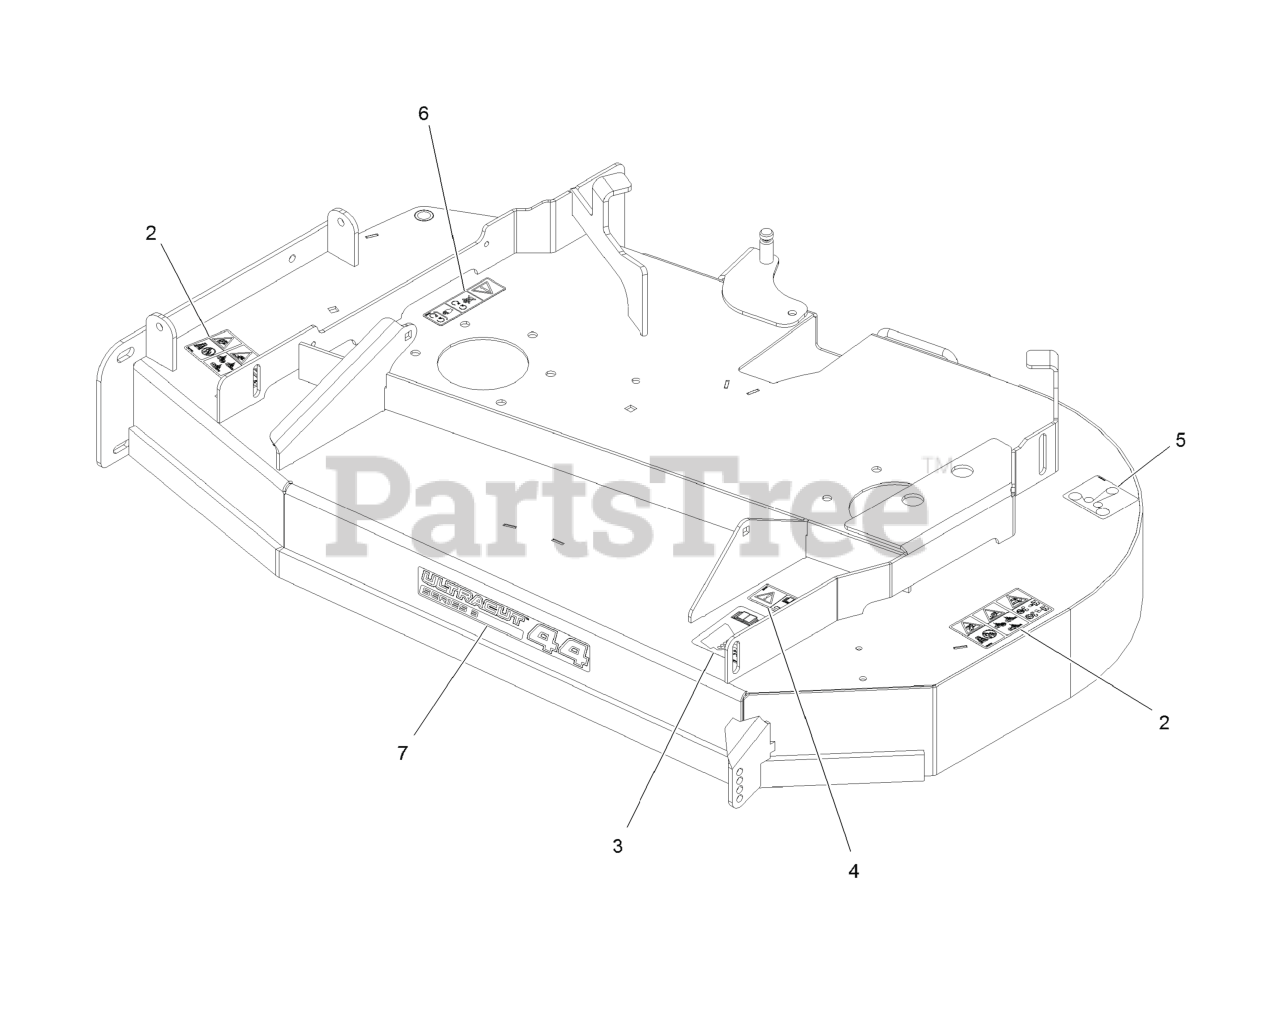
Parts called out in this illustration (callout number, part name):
2	DECAL-DANGER THROWN OBJECTS
3	DECAL-ROLLER, ANTI-SCALP
4	DECAL-TORQUE, BOLT
5	DECAL-ROUTING, BELT
6	DECAL-COVER, MISSING
7	DECAL-ULTRACUT 44 SERIES 3
